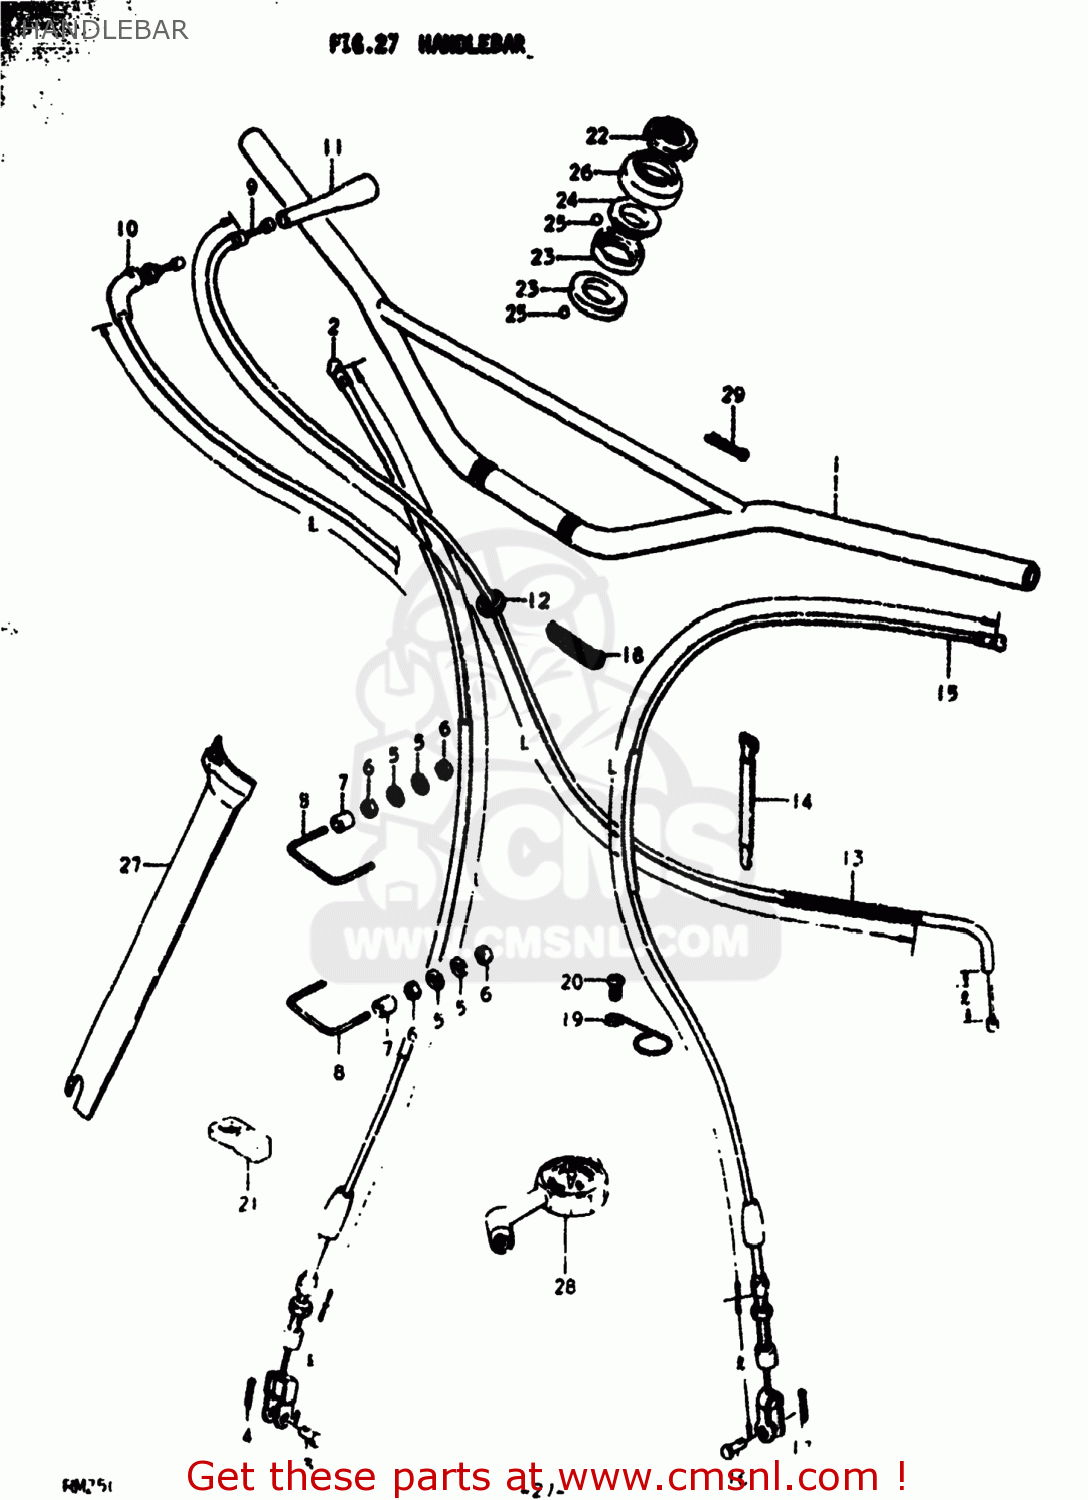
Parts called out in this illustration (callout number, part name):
1	HANDLEBAR
2	CABLE ASSY,FR BRAKE
3	PIN(L:13)
4	PIN
5	WASHER
6	NUT 3MM
7	BUSHING
8	CLAMP,CABLE
9	CABLE ASSEMBLY,THROTTLE
10	CABLE ASSEMBLY,THROTTLE
11	SEAL
12	GROMMET
13	PROTECTOR,CABLE
14	CLAMP
15	CABLE ASSEMBLY,CLUTCH
16	PIN(L:13)
17	PIN
18	CLAMP L:35
19	CLAMP
20	SCREW 6X12
21	GUIDE,CABLE
22	NUT,STEERING STEM(25X44X10)
23	LACE,STEERING INNER LWR
24	LACE,STEERING OUTER UPR
25	BALL
26	DUST SEAL,STEERING UPR
27	PROTECTOR
28	GAUGE ASSEMBLY,AIR PRESSURE
29	COTTER PIN
